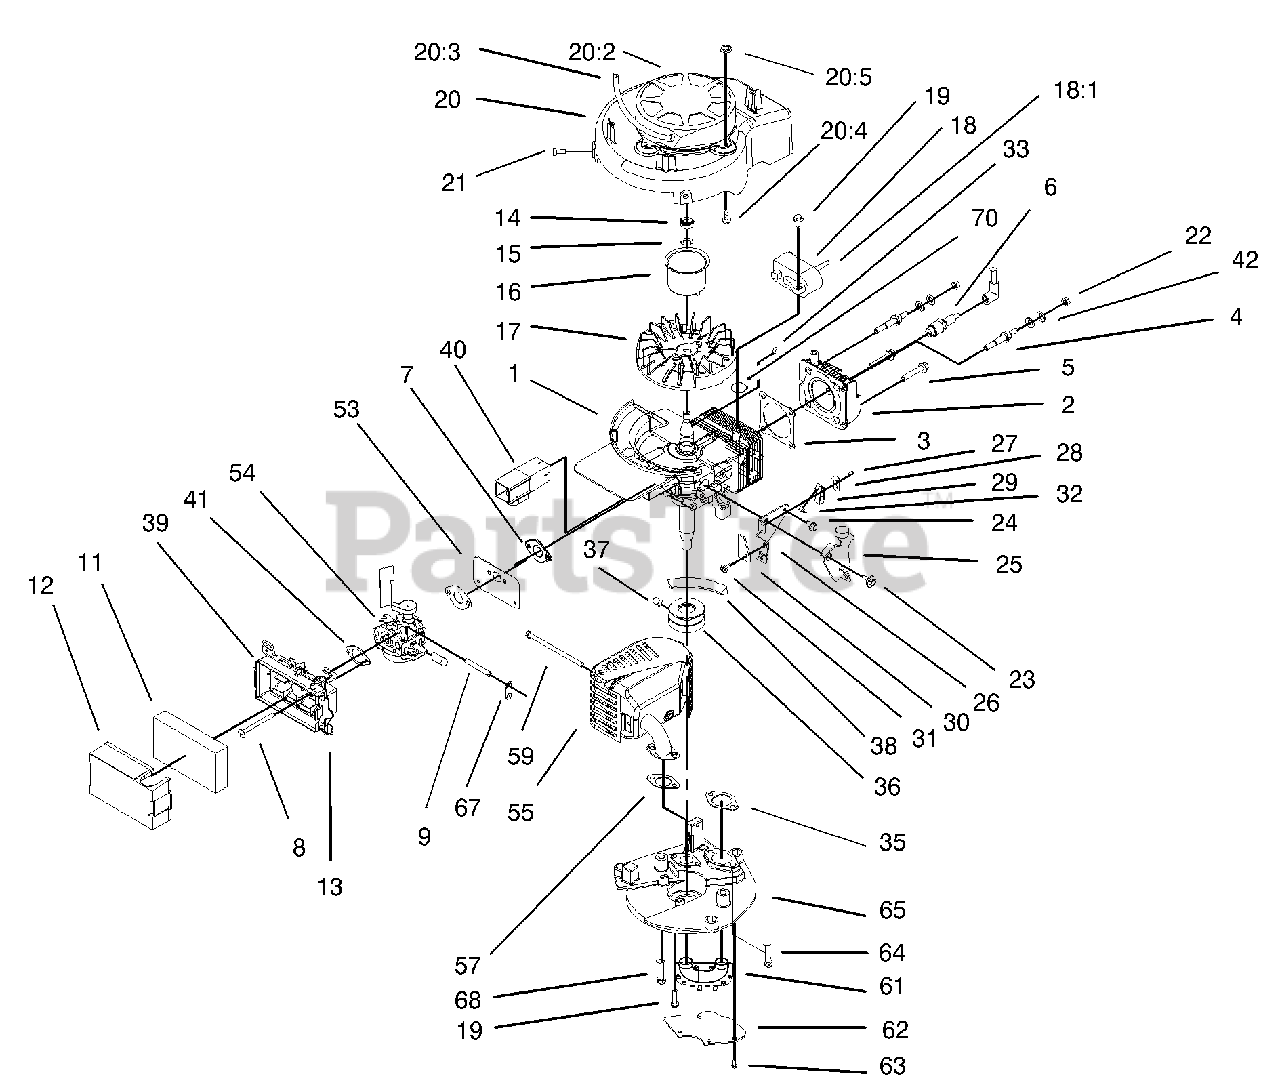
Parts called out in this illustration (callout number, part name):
1	SHORT BLOCK ASM
2	HEAD-CYLINDER
3	GASKET-HEAD
5	SCREW-HWH
6	SPARK PLUG
7	GASKET-INTAKE
9	HOSE-PRIMER
11	FILTER-AIR
12	COVER-FILTER, AIR
13	RETAINER-COVER, FILTER
15	WASHER-LOCK
16	CUP-STARTER
17	FLYWHEEL
18	MODULE-IGNITION
18:2	LEAD-TENSION, HIGH
20	SHROUD-RECOIL
20:2	RECOIL ASM
20:3	ROPE-RECOIL
20:4	SCREW-HWH
20:5	NUT-LOCK
21	SCREW-HH
23	SCREW-SHOULDER
24	SCREW-HWH
25	PLATE-BRAKE
26	PLATE-BRAKE
27	RIVET-PLASTIC
28	STRAP-INSULATION
29	STRAP-GROUND
30	STOP-STRAP, GROUND
32	LEAD WIRE-SWITCH, BRAKE
35	GASKET-EXHAUST
37	SCREW-SET
39	AIR BASE ASM
40	TUNNEL-INLET
41	GASKET-FILTER
42	WASHER-BELLEVILLE
53	SHIELD-CARB
54	CARBURETOR ASM
54	Carburetor Asm
55	MUFFLER AND GUARD
59	BOLT-CONSOLE
61	PIPE-TRANSFER
62	COVER-MUFFLER
63	SCREW-HH
64	SCREW-HH
65	PLATE-MUFFLER
67	HOSE-RETAINER
68	SCREW-HH
70	STRAP-TIE
